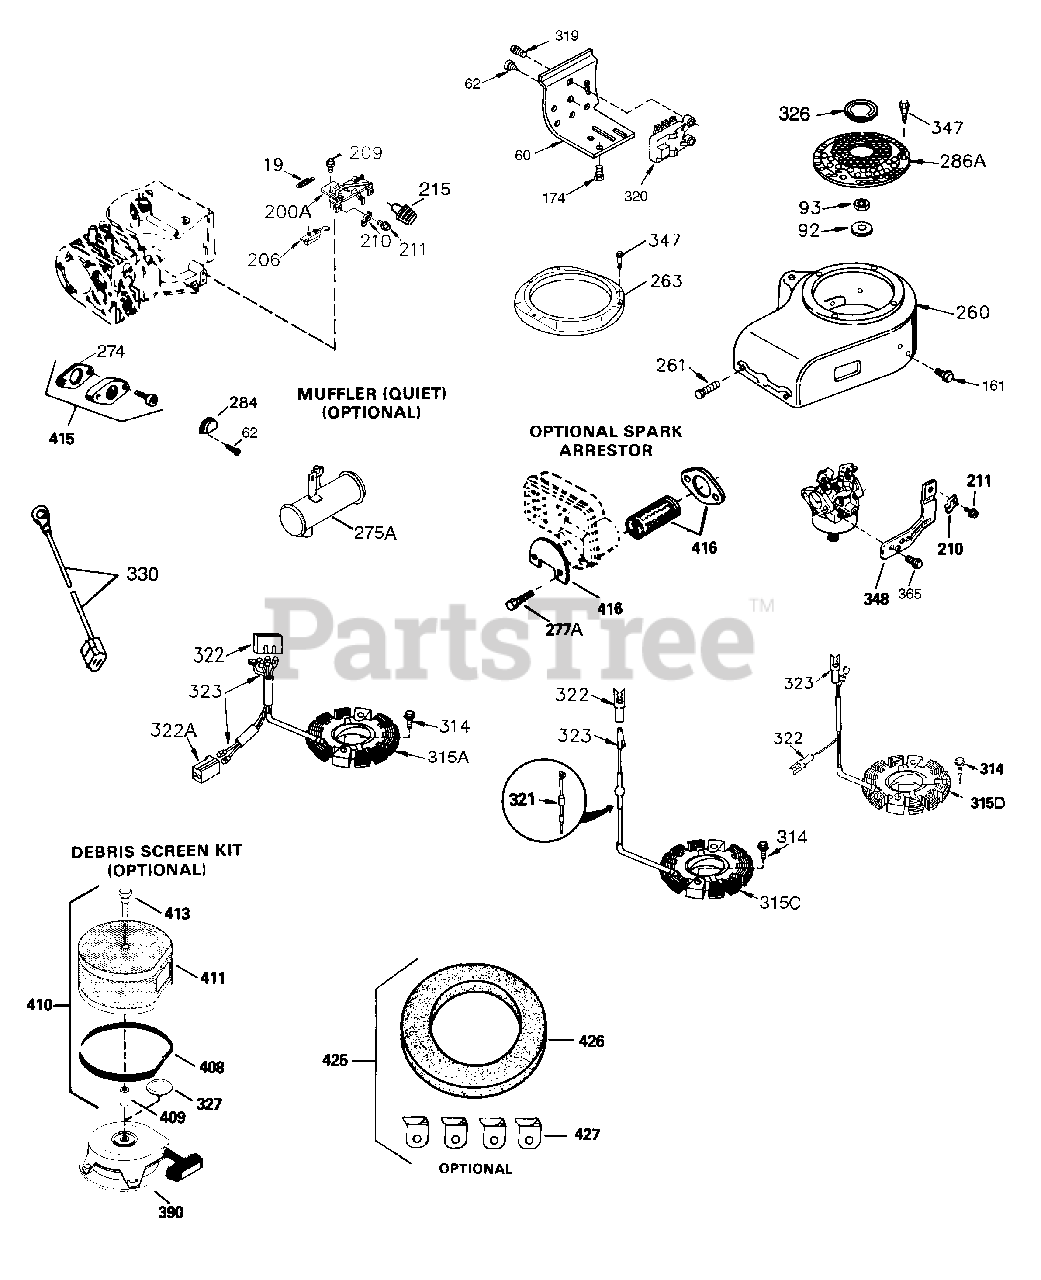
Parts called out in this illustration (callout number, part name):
19	Extension Spring
41	Piston & Pin Assembly (Std) (Incl. 43 )
41	Piston & Pin Ass'y. (.010" OS) (Incl. 43)
41	Piston & Pin Ass'y. (.020" OS) (Incl. 43)
60	Blower Housing Extension
62	Screw, 8-32 x 3/8"
92	Lock Washer
93	Flywheel Nut
174	Screw, 10-24 x 1/2"
210	Conduit Clip
211	Screw, 10-32 x 3/8"
243	Screw, 10-32 x 7/16"
260	Blower Housing
261	Screw, 5/16-18 x 3/4"
263	Trim Ring
286A	Cup & Screen
314	Screw, 1/4-20 x 3/4"
319	Screw, 10-24 x 3/8"
320	Regulator (5 Amp D.C.)
322	Connector Body
323	Terminal
323A	Terminal
323B	Terminal
326	Screen Plug
347	Screw, 10-32 x 9/16"
900	Rep. engine 752289C, order from 71-99 9
